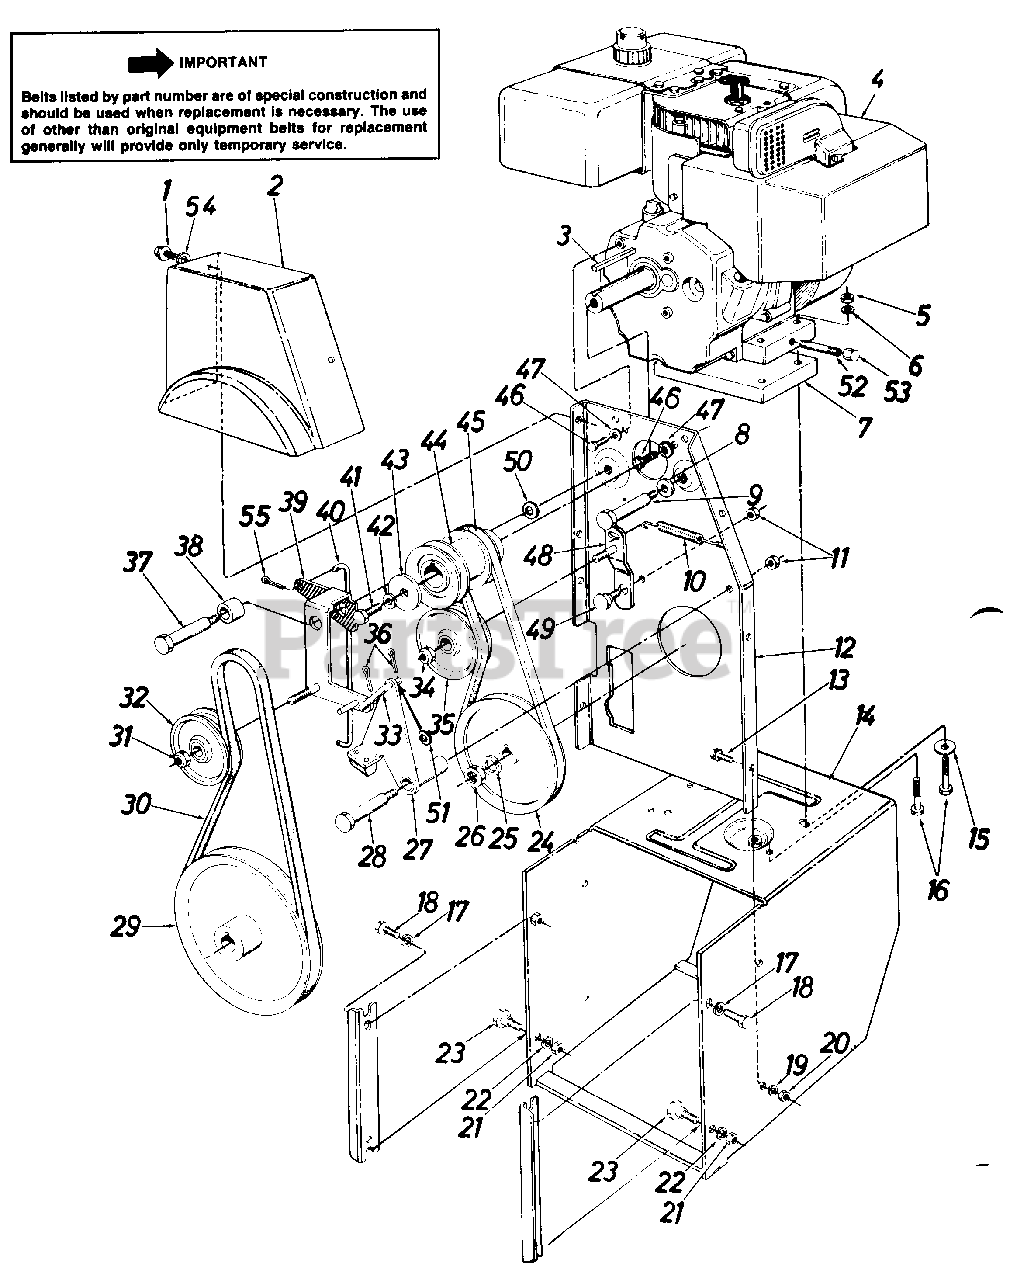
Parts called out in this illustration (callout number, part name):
1	Hex AB-Tap Scr. 5/16 x .75" Lg.
2	Belt Cover
3	Sq. Key 1/4" x 1.50" Lg.
4	Engine
5	Hex Nut 5/16-18 Thd.
6	L-Wash. 5/16" I.D.
7	Engine Spacer Ass'y.
8	Bell-Wash. .40 I.D. x .88 O.D.
9	Shld. Bolt 498" Dia. x 3.001" Lg.
10	Ext. Spring .38 O.D. x 3.18" Lg.
11	Hex Cent. L-Nut 3/8-16 Thd.
12	Engine Brkt. Ass'y.
13	Hex Sems Scr. 5/16-18 x .75" Lg.
14	Frame Ass'y.
15	Fl-Wash. .345 I.D. x .75 O.D. x .060
16	Hex Bolt 5/16-18 x 2.50" Lg.
17	L-Wash. 3/8" I.D. H.D.
18	Pilot Scr. 3/8-16 x .88" Lg.
19	L-Wash. 5/16" I.D.
20	Hex Nut 5/16-18 Thd.
21	Hex Nut 3/8-16 Thd.
22	L-Wash. 3/8" I.D. H.D.
23	Shld. Bolt .498" Dia. x .340" Lg.
24	V-Pulley .628 I.D. x 7.50 O.D.
25	L-Wash. for 5/8" I.D.
26	Hex Ins. Jam L-Nut 5/8-18 Thd.
27	Brake Brkt. Ass'y.
28	Shld. Bolt .498" Dia. x 2.00" Lg.
29	V-Pulley .875 I.D. x 10.12 O.D.
30	"V"-Belt
31	Hex Ins. Jam L-Nut 3/8-24 Thd.
32	Fl-Idler w/Flanges 3.0 O.D.
33	Brake Linkage Ass'y.
34	Hex Ins. Jam L-Nut 3/8-24 Thd.
35	3.0" O.D. Fl-Idler w/Flanges
36	Int. Cot. Pin 3/32" Dia.
37	Shld. Bolt .625" Dia. x 2.750" Lg.
38	Spacer .75 O.D. x 1.00" Lg.
41	Hex Bolt 3/8-24 x 1.25" Lg.
42	L-Wash. 3/8" I.D. H.D.
43	Fl-Wash.
44	Engine Pulley Double Groove
45	"V"-Belt
46	Hex Bolt 5/16-24 x .62" Lg.
47	Bell-Wash. .345 I.D. x .88 O.D. x .060
48	Drive Idler Brkt. Ass'y.
49	Shld. Bolt .625" Dia. x .170" Lg.
50	Bell-Wash. .40 I.D. x 1.12 O.D.
51	Fl-Wash. .385" I.D. x .620" O.D.
52	Pipe Nipple 1/4" Pipe Thd. x 35" Lg.
53	Hex Hd. Cap 1/4-18 Pipe Thd.
54	Fl-Wash. .340 I.D. x .62 O.D. x .62
55	Int. Cot. Pin 5/16" Dia.
